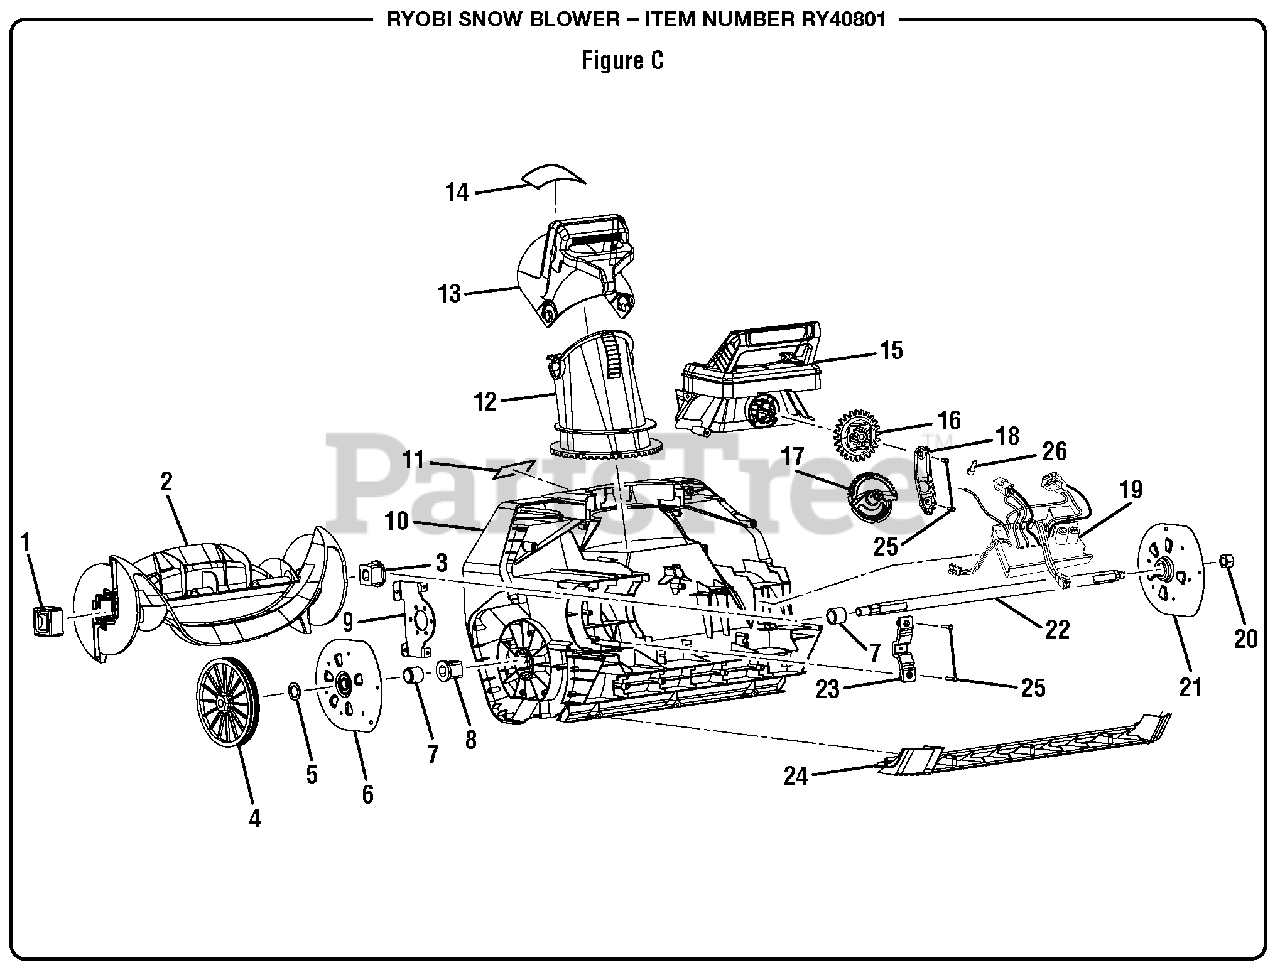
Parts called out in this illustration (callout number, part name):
1	Connect plate
3	Block (Right)
5	Washer (ID15.4 x OD24 x 1.7t )
6	Bearing Plate Assembly (Left)
8	Block (Left)
10	Front Housing
11	Chute Logo Label
13	Chute Assembly
14	Chute Icon Label
15	Housing Handle
17	Gear (Large)
19	Circuit Board Assembly
21	Bearing Plate Assembly (Right)
23	Mounting Plate
25	Screw (M4.2 x 16 mm)
26	Wire Connector
